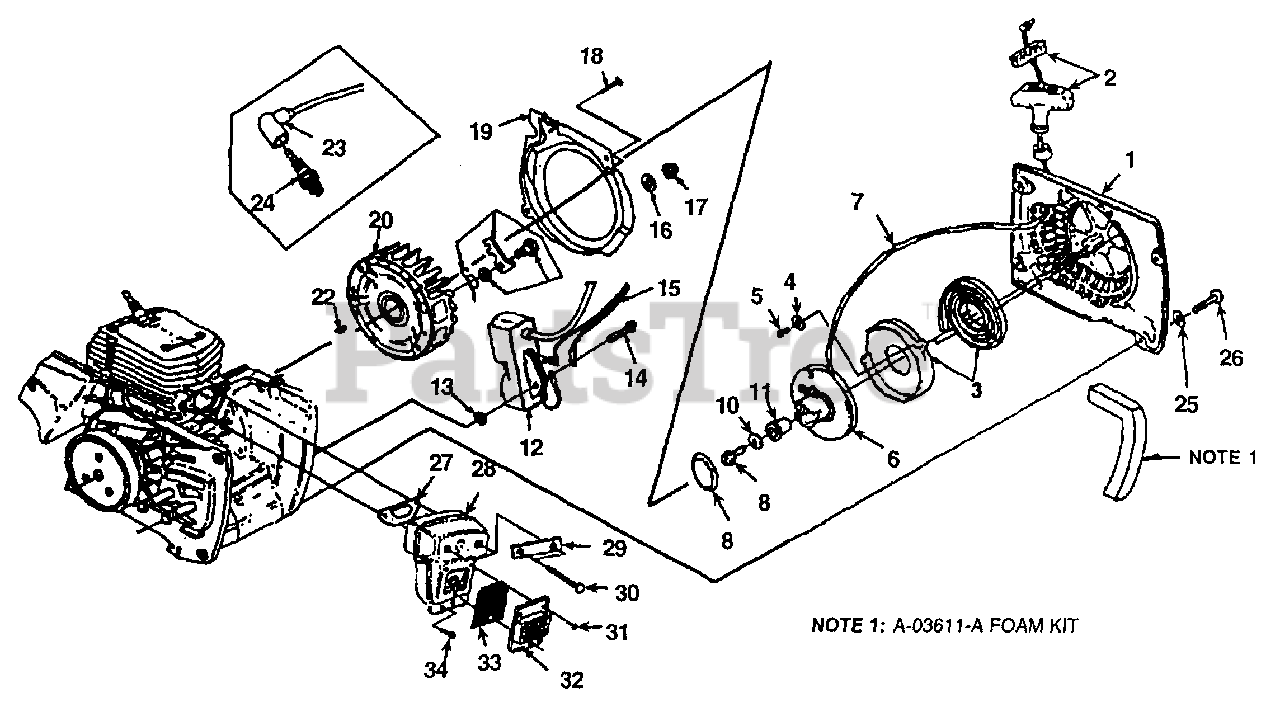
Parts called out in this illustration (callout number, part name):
1	STARTER COMPLETE
2	GRIP - W/INSERT
3	SPRING & RETAINER
4	WASHER - FLAT (#8)
5	SCREW - THREAD FORM (6 X 3/8")
6	PULLEY & ROPE
7	ROPE
8	SPRING - GRIP
10	WASHER - RETAINING
11	BUSHING - STARTER POST
12	MODULE ASSY
14	SCREW - HEX HD (10-24 X 7/8")
15	LEAD - GROUND W/GROMMET
16	WASHER - FLAT
17	NUT - LOCK HEX (3/8-24)
18	SCREW MACH (8-32 X 5/8")
19	SCROLL - AIR GUIDE
20	ROTOR
22	KEY - WOODRUFF
23	TERMINAL - SPARK PLUG
24	SPARK PLUG (RCJ6Y)
25	WASHER - FLAT (#10)
26	SCREW - PAN HD (10-24 X 5/8")
27	GASKET - MUFFLER
28	MUFFLER
29	PLATE - RETAINING
30	SCREW - HEX CAP (1/4-20 X 3 1/4")
31	SCREW - MACH (8-32 X 1/2")
32	CAP - MUFFLER
33	SCREEN - SPARK ARRESTOR
34	SCREW - TRUSS HD (10-24 X 3/4")
